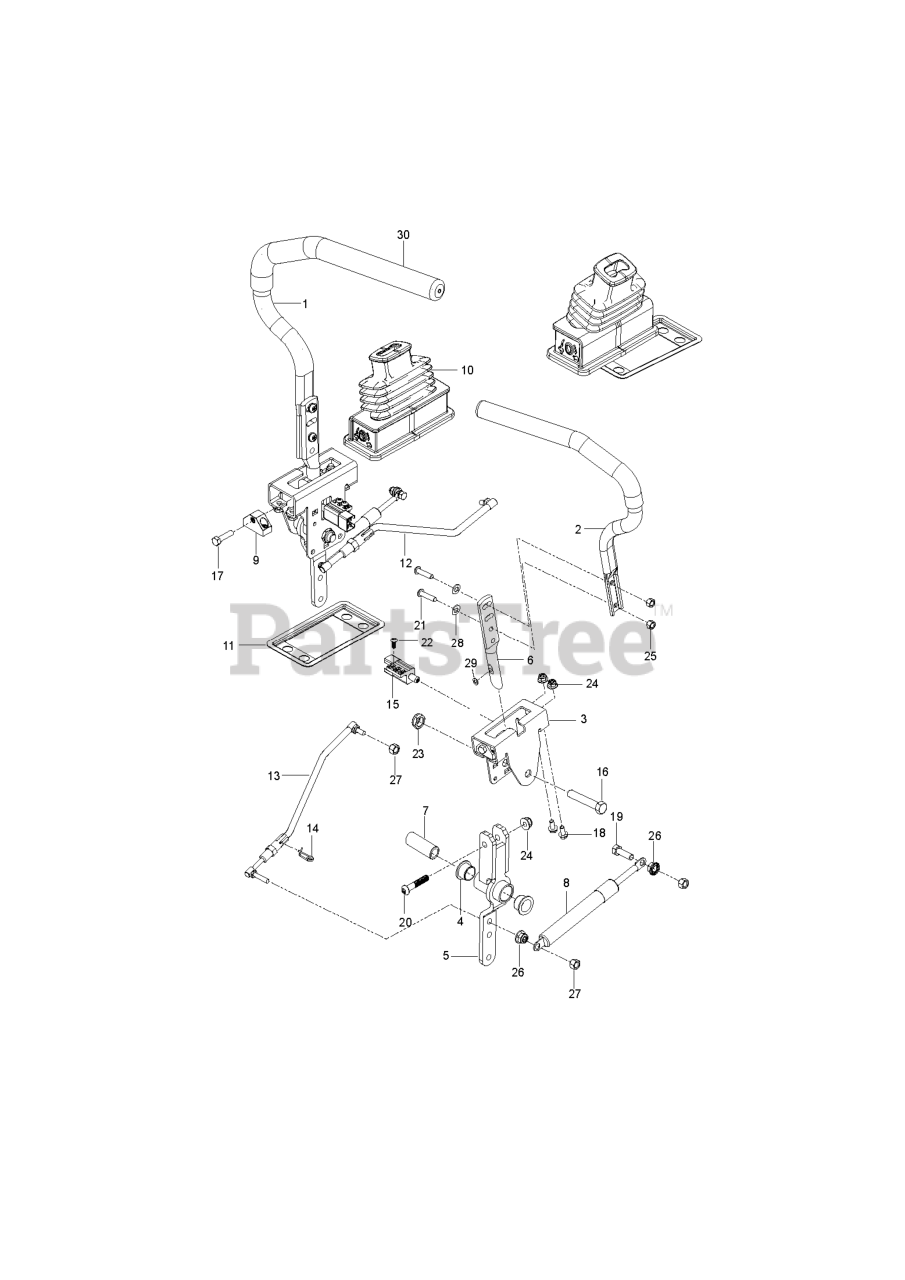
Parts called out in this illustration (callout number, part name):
1	TUBE.LEVER.CNTL.ASM.ZTR.RT.SVC
2	TUBE.LEVER.CNTL.ASM.ZTR.LT.SVC
3	BRACKET.CONTROLS.ZTR.X431
4	BEARING, FLANGE
5	LEVER CONTROL PIVOT
7	SPACER.PIVOT.CONTROL
10	BOOT.STEERING.LEVER
11	CONTROL.BOOT.FLANGE.X431
12	ROD.ASM.RH.ADJUSTABLE
12	Controls
13	Rods
13	ROD.ASM.LH.ADJUSTABLE
14	RETAINER.CLIP.SPRING.S
15	SWITCH.INTLK.RZ.RFRSH.BUTTON
16	Bolts
16	HCS 1/2-13 X 2-3/4 GD 5 ZD
17	SCREW.SHAKEPROOF.1.25.BLACK
18	Bolts
18	HHFS 5/16-18 X 3/4
19	Bolts
19	HCS 5/16C X 1
20	SCREW 5/16-18 X 1 3/4 BTN-HD
20	SCREW.CAP.SOCKET.6PT.5/16-18
21	BUTTONHEAD.5/16-18X1.125.BLACK
22	SCR #10-24 X .75 SKT HD BLK
23	NUT 1/2-13 HEX JM NYL
24	NUT HEXAGON FLANGE 5/16-18 ST
24	5/16-18 NYLOC FLANGE NUT
25	Nuts
25	NYLOCK.NUT.5/16-18 BLACK
26	GSPW Hardware
26	NUT 5/16C WHIZ
27	NUT.71038.31-18.HEX.NYLOCK
27	Nuts
28	WASHER.11/32X11/16 BLACK
28	WASHER 11/32 X 11/16 X 14 GA T
28	WASHER
29	WASHER.11/32ID.11/16OD.116THIC
30	PURCHASE THE COMPLETE LEVER
